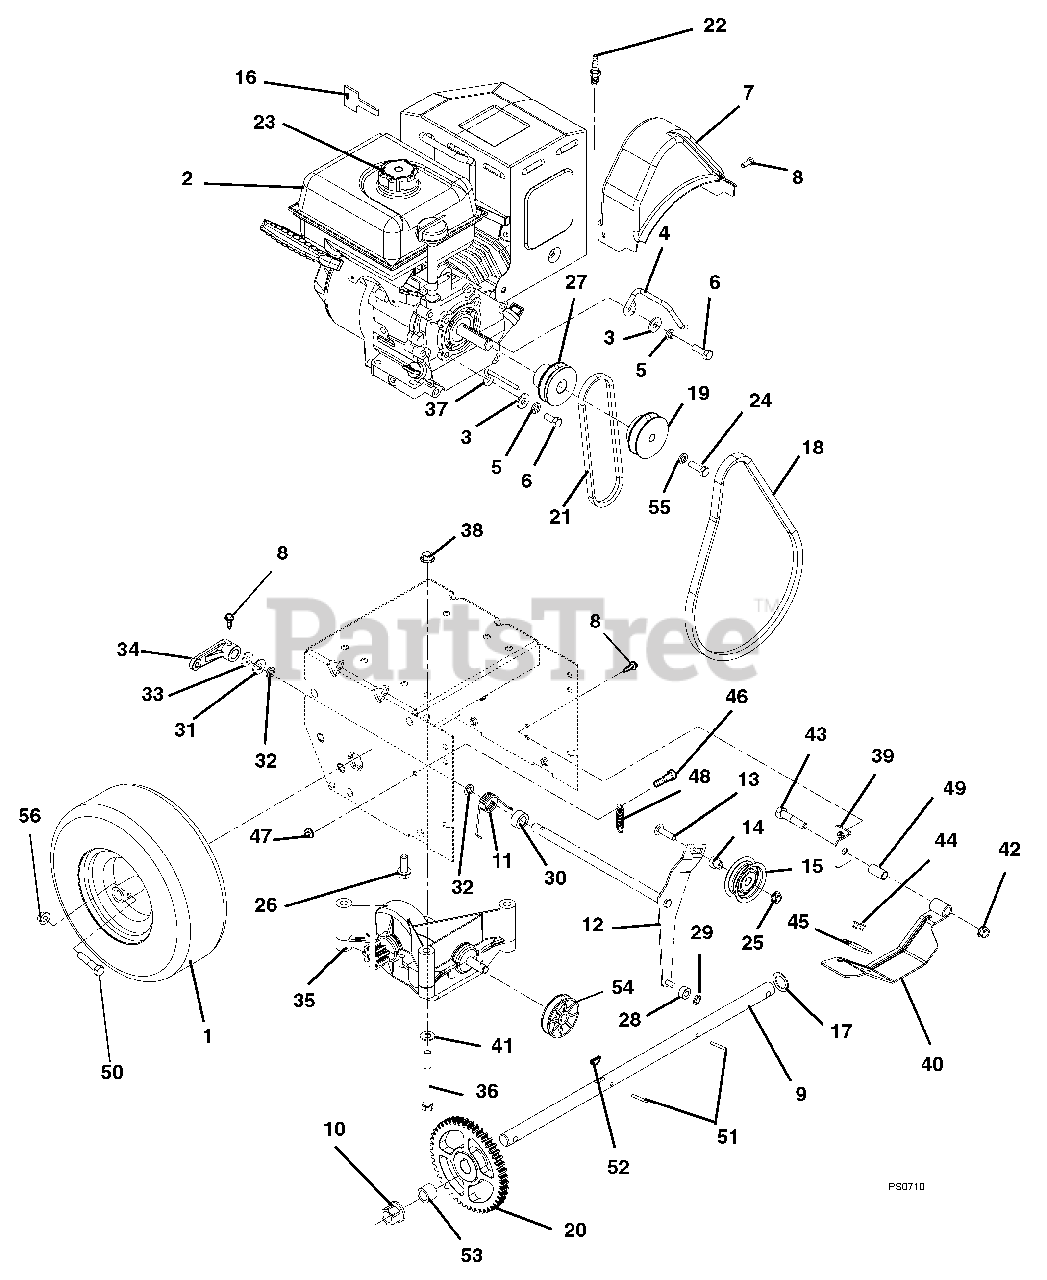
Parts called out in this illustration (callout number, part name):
1	TIRE/WHEEL, 13X4.10-6 K398A
2	ENGINE,LCT STORMFORCE 208 RECL
3	@WSHR-FL-STL.38X.875X.083 YWZC
4	FINGER, BELT
5	WSHR-LK .312X.097 HVY YWZC
6	BLT-HEX .31-24X.75 YWZC GR5
7	COVER, BELT
8	@SCR-TAP .25-20X.50 HWH TR YWZ
9	AXLE, 939,XXX W/LG TIRES
10	BSHG-FLG .750X.873HEXX.53X1.18
11	SG-TORS .067X.88
12	WELDMENT, ATTACHMENT IDLER ARM
13	@BLT-RHDSHSQNK.31-18X1.25 G5YZ
14	SPCR, BRG .315X.50X.688X.281
15	IDLER
16	KEY, PUSH/PULL LCT (2/PACKAGE)
17	WSHR-FL-STL.754X1.125X.062YWZC
18	V-BELT, 4L-RAW EDGE
19	SHEAVE, ENGINE
20	GEAR, AXLE 45T
21	V-BELT, 3L-STRETCH FIT
22	PLUG, SPARK
23	CAP, FUEL TANK BLACK
24	BLT-HEX .38-24X1.0 YWZC GR5
25	@NUT-LK-TOP-FLG .31-18 YWZC
26	SCR-TAP .38-16X1.0 HWH YZ W/VT
27	SHEAVE, DRIVE
28	BSHG,SLV .270 X .750 X .250
29	RG-RTNG-EXT .250X.010
30	BSHG-SLV .510X.751X.475
31	WSHR-FL-STL .52X.827X.062 YWZC
32	BUSHING, POLYLINER-.50 SNAPIN
33	WSHR-WAVE .50X.75X.015 .13FRHT
34	ARM, CLUTCH - ATTACHMENT
35	TRANSMISSION, FR SS
36	@BLT-HEX .38-16X3.50 GR5 YWZC
37	BELT FINGER
38	NUT-LK-CTR-FLG .38-16 YWZC
39	BRACKET, MOUNT - BRAKE
40	ARM, BRAKE
41	@WSHR-FL-STL.406X.812X.065 YWZ
42	@NUT-LK-TOP-FLG .38-16 YWZC
43	@BLT-HEX .38-16X1.75 GR5 YWZC
44	RVT-POP .187 YZ
45	PAD, BRAKE
46	BLT-SHLDR .31X.50 .25-20X.438
47	@NUT-SPNLK-FLG .25-20 YWZC
48	SG-TENS .06X.46X2.00
49	BSHG-SLV .385X.500X1.045
50	@BLT-HEX .31-18X1.50 GR5 YWZC
51	PIN-ROLL .188X1.25
52	KEY-WDRF .25X.750X.313 SAE91
53	BSHG-SLV .75X1.12X1.062 NYL BK
54	PULLEY, COMPOSITE 3L INPUT
55	@WSHR-LK .38X.094 REG YWZC
56	@NUT-LK-CTR-FLG .31-18 YZ GR F
